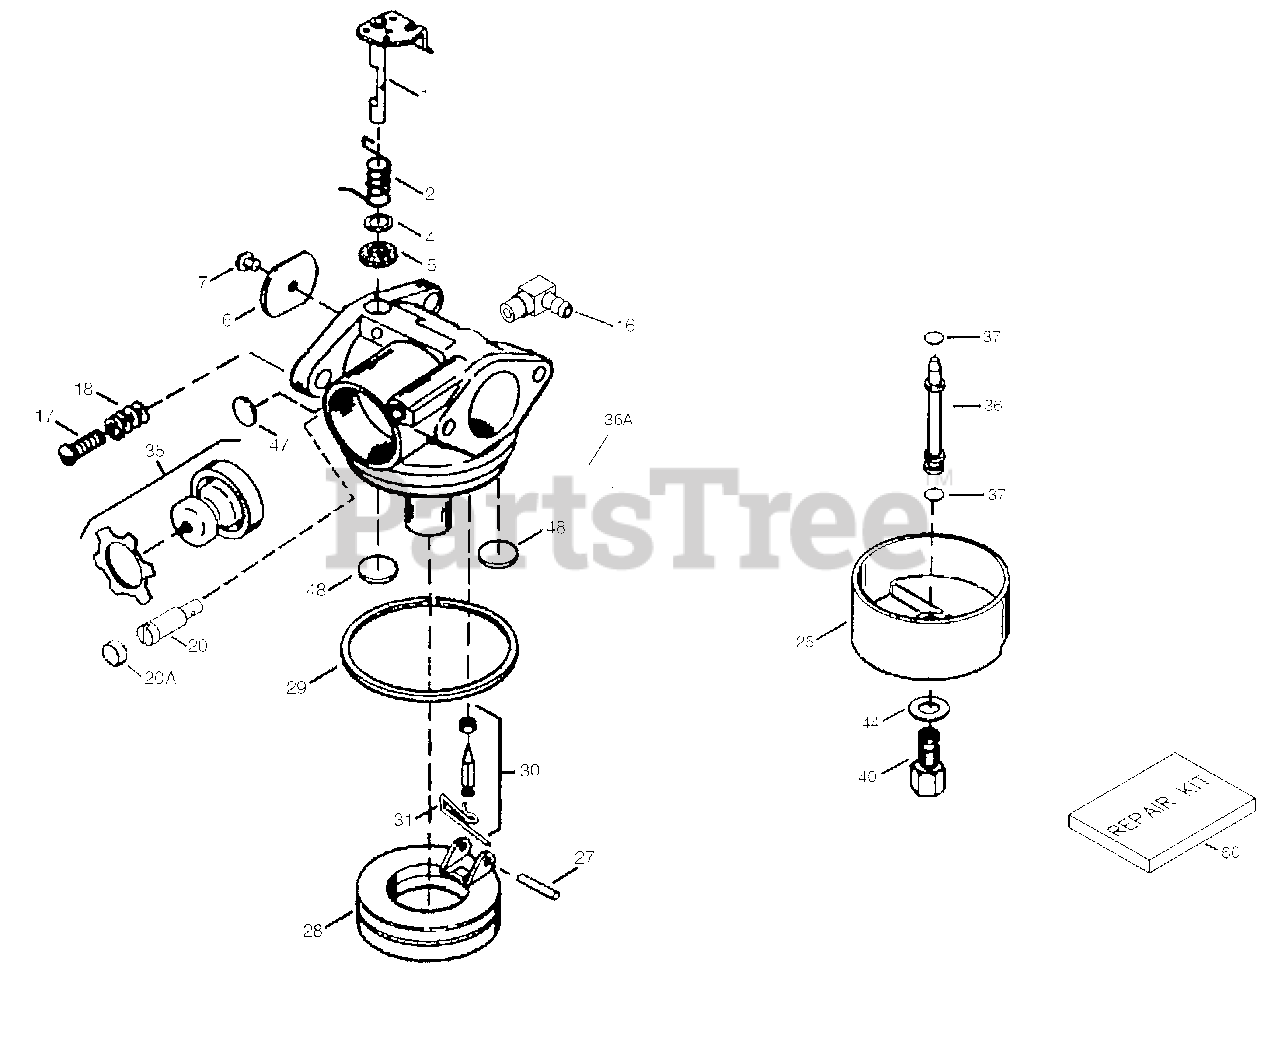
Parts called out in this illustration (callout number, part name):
1	Throttle Shaft & LeverAssembly
2	Throttle Return Spring
4	Dust Seal Washer
5	Dust Seal (Throttle)
6	Throttle Shutter
7	Shutter Screw
16	Fuel Fitting
17	Throttle Crack Screw/Idle Speed Screw
18	Tension Spring
20	Idle Restrictor Screw
20A	Idle Restrictor Screw Cap
25	Float Bowl
27	Float Shaft
28	Float
29	Float Bowl "O" Ring
30	Inlet Needle, Seat, & Clip (Incl. 31)
31	Spring Clip
35	Primer Bulb/RetainerRing
36	Main Nozzle Tube
36A	Bowl Vent Tube Extension
37	O-Ring, Main Nozzle Tube
40	High Speed Bowl Nut
44	Bowl Nut Washer
47	Welch Plug, Idle Mixture Well
48	Welch Plug, Atmospheric Vent
60	Repair Kit
